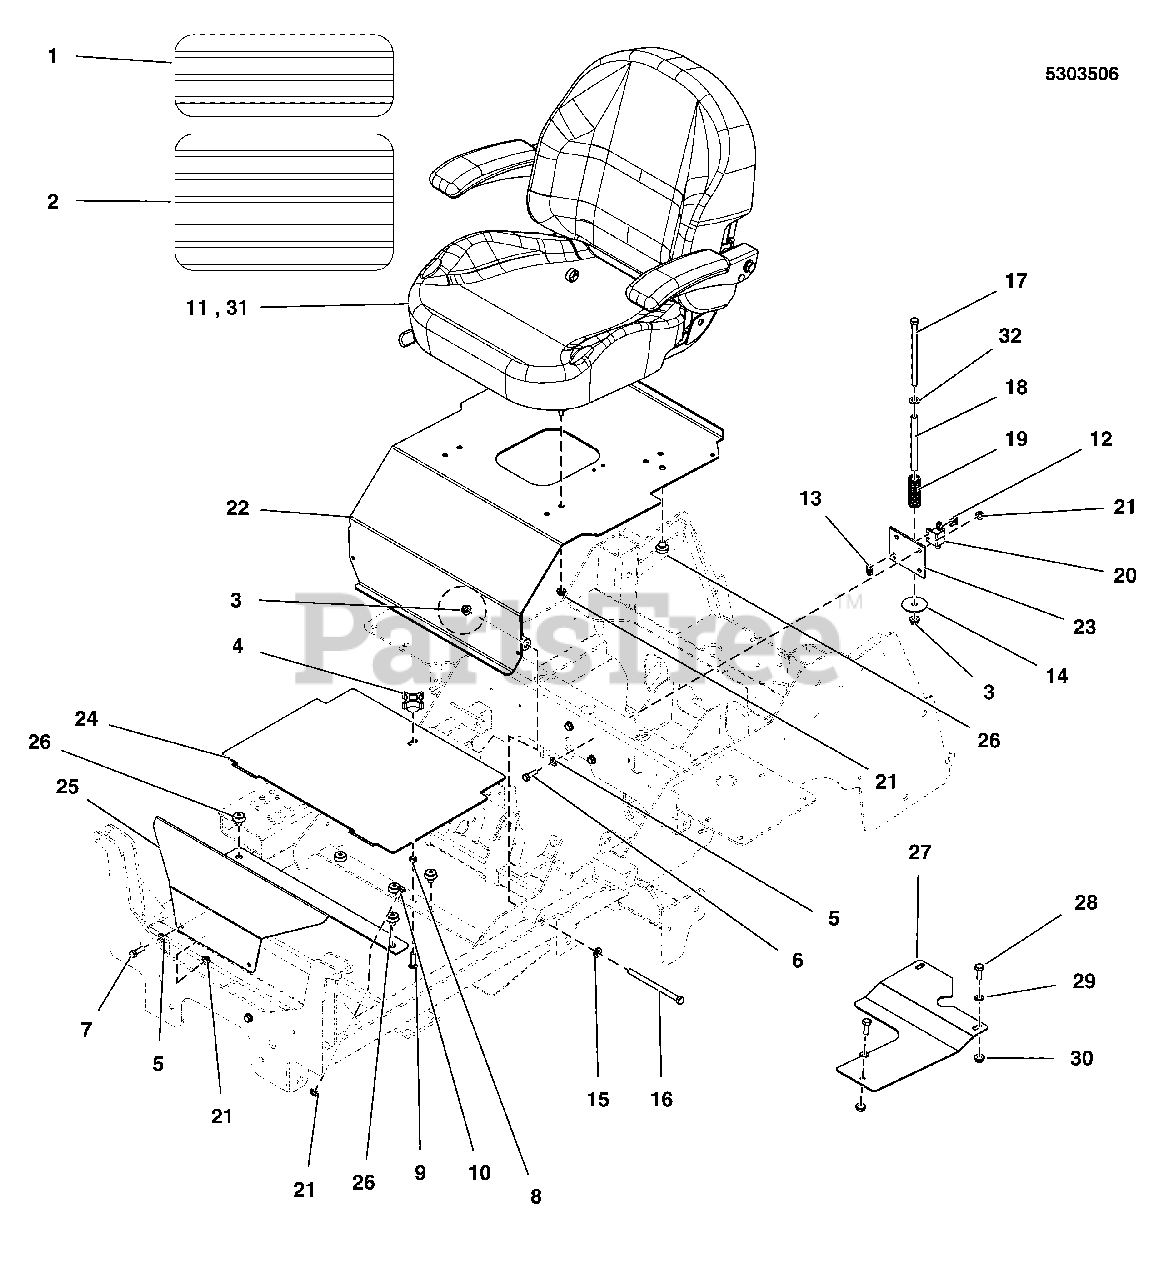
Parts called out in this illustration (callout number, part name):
1	SAFETY WALK, FLOOR REST, 6.00 X 16.00
2	SAFETY WALK, FLOOR PLATE, S50X, 10X16
3	NUT, 3/8-16 HEX NYLOCK FLANGE
4	KNOB-INT THR .312-18 4-ARM 2.12WD 1.06LG
5	WASHER, 5/16" SAE
6	BOLT, 5/16-18 X 1 GD5 YZ
7	BOLT, 5/16-18 X 3/4 GD5
8	NUT, 5/16-18, HEX, CNTR LK,ZINC PHOS/OIL
9	BOLT, 5/16-18 X 1-1/4, CARRIAGE YZ
10	BOLT, 5/16-18 X 3/4, CARRIAGE
11	SEAT, 2012
12	SCREW, #10-24 X 3/4 ROUND PHILLIPS
13	NUT, #10-24 HEX
14	WASHER, .39 X 2.00 X X .14
15	WASHER, 3/8 SAE
16	BOLT, 3/8-16 X 5-1/2" GD5 CZ
17	BOLT, 3/8-16 X 6" GD5 CZ
18	SPACER, .38 X .50 X 5.06
19	SPRING, .688 ID X .130 WIRE DIA 4.25
20	SWITCH (SEE ELECTRICAL GROUP)
21	NUT, 5/16-18 HEX NYLOCK FLANGE
22	ASSM, SEAT PLATE W/ DECALS, IS2100Z (SV)
22	ASSM, SEAT PLATE W/ DECALS, IS2100Z EXP (SV)
23	WELD, SEAT SWITCH
24	PLATE, FLOOR, REMOVABLE, IS2000 - RED
25	PLATE, FRONT FLOOR, IS2000 - RED
26	MNT, VBRTN, RBBR
27	GUARD, DEBRIS, IS2100Z - BLK
28	BOLT, 1/4-20 X 3/4 GD5 YZ
29	WASHER, 1/4 SAE
30	NUT, 1/4-20 HEX SERR. FLANGE
31	SEAT, CI3, SEAT'S INC. 2016
32	WASHER, 3/8 USS
